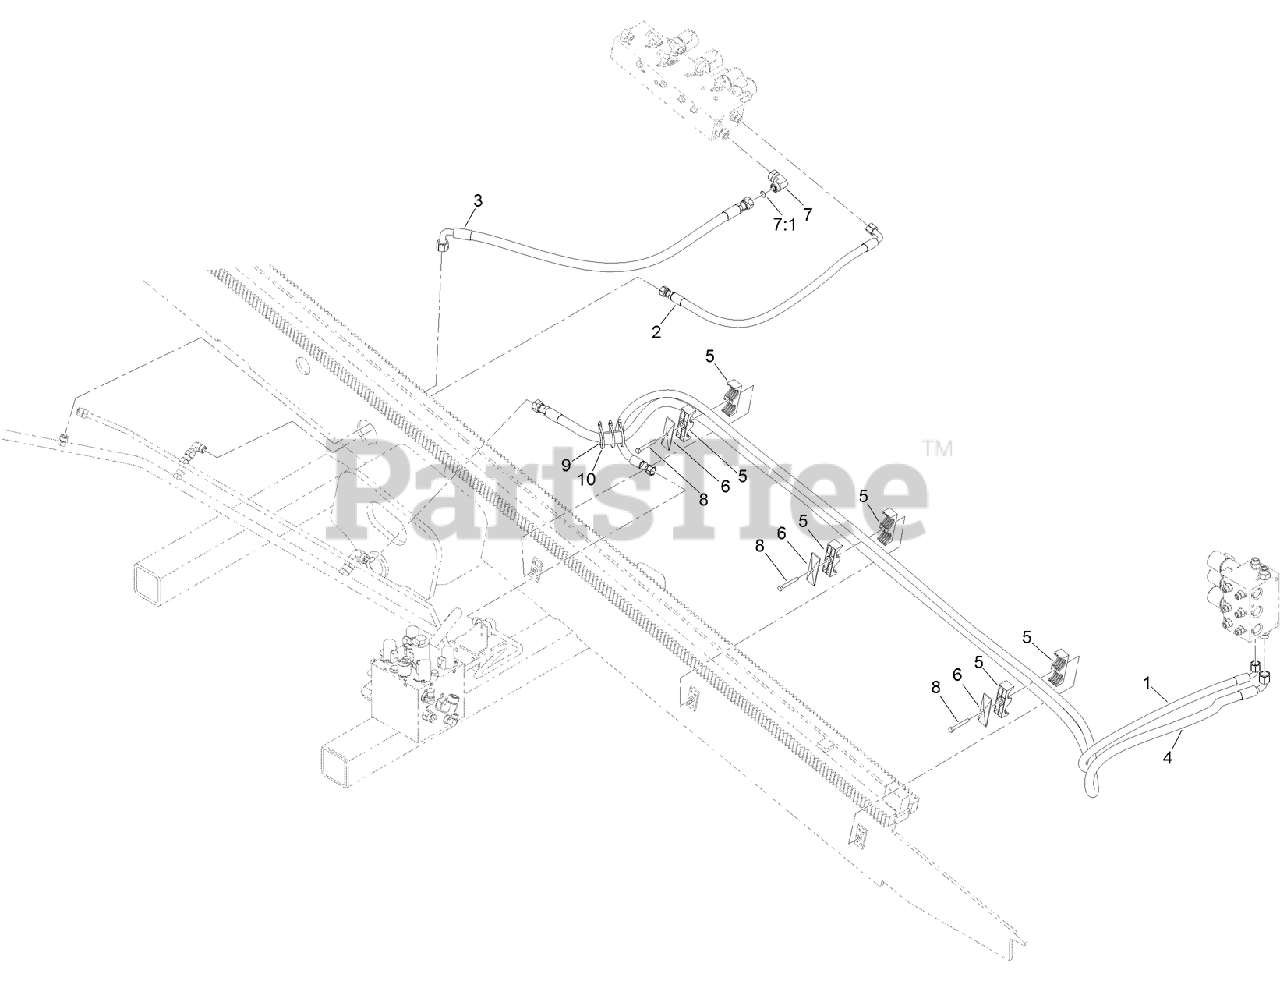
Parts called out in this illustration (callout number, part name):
1	HOSE-HYD
2	HOSE-HYD
3	HOSE-HYD
4	HOSE ASM-HYD
5	CLAMP-TWIN
6	PLATE-REATAINER, CLAMP
7	FITTING-HYD-90
7:1	O-RING
8	SCREW-HH
9	PROTECTOR-HOSE
10	TIE-CABLE
